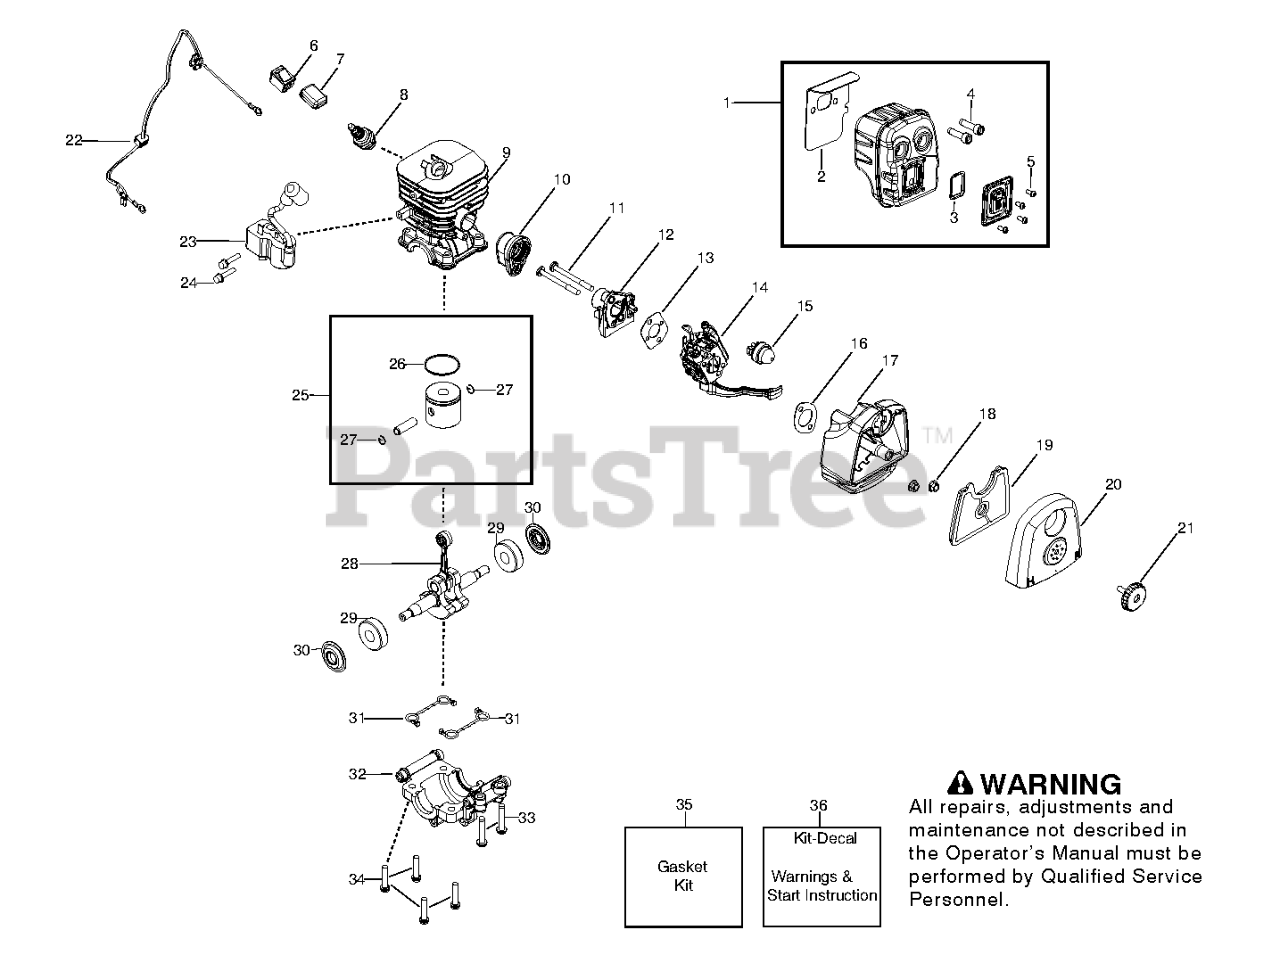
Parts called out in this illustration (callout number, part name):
1	ASSY, MUFFLER
3	KIT, SPARK SCREEN
4	BOLT MUFFLER
5	SCREW-6-19X5/16PLAST PA
6	KIT SWITCH
7	PROTECTOR, SWITCH
8	PLUG-SPARK (RCJ-6Y)
9	CYLINDER -CHROME
10	BOOT, CARB
12	PLATE, CARB
14	KIT, CARB
15	AIR PURGE
17	BASE - AIR BOX
19	FILTER, AIR
20	COVER - AIR BOX
21	ASSY - AIR BOX KNOB
22	ASSY, LEADWIRE
23	IGNITION MODULE
24	SCREW M4 X .70 TT 16MM
25	KIT - PISTON
26	RING PISTON
27	WRIST PIN RET.
28	KIT, CRANKSHAFT
29	BEARING RADIAL BALL (6201)
30	CRANKSHAFT SEAL
32	CAP - BEARING
34	B0LT, C/SHAFT 36/41
35	GASKET
36	KIT DECAL
